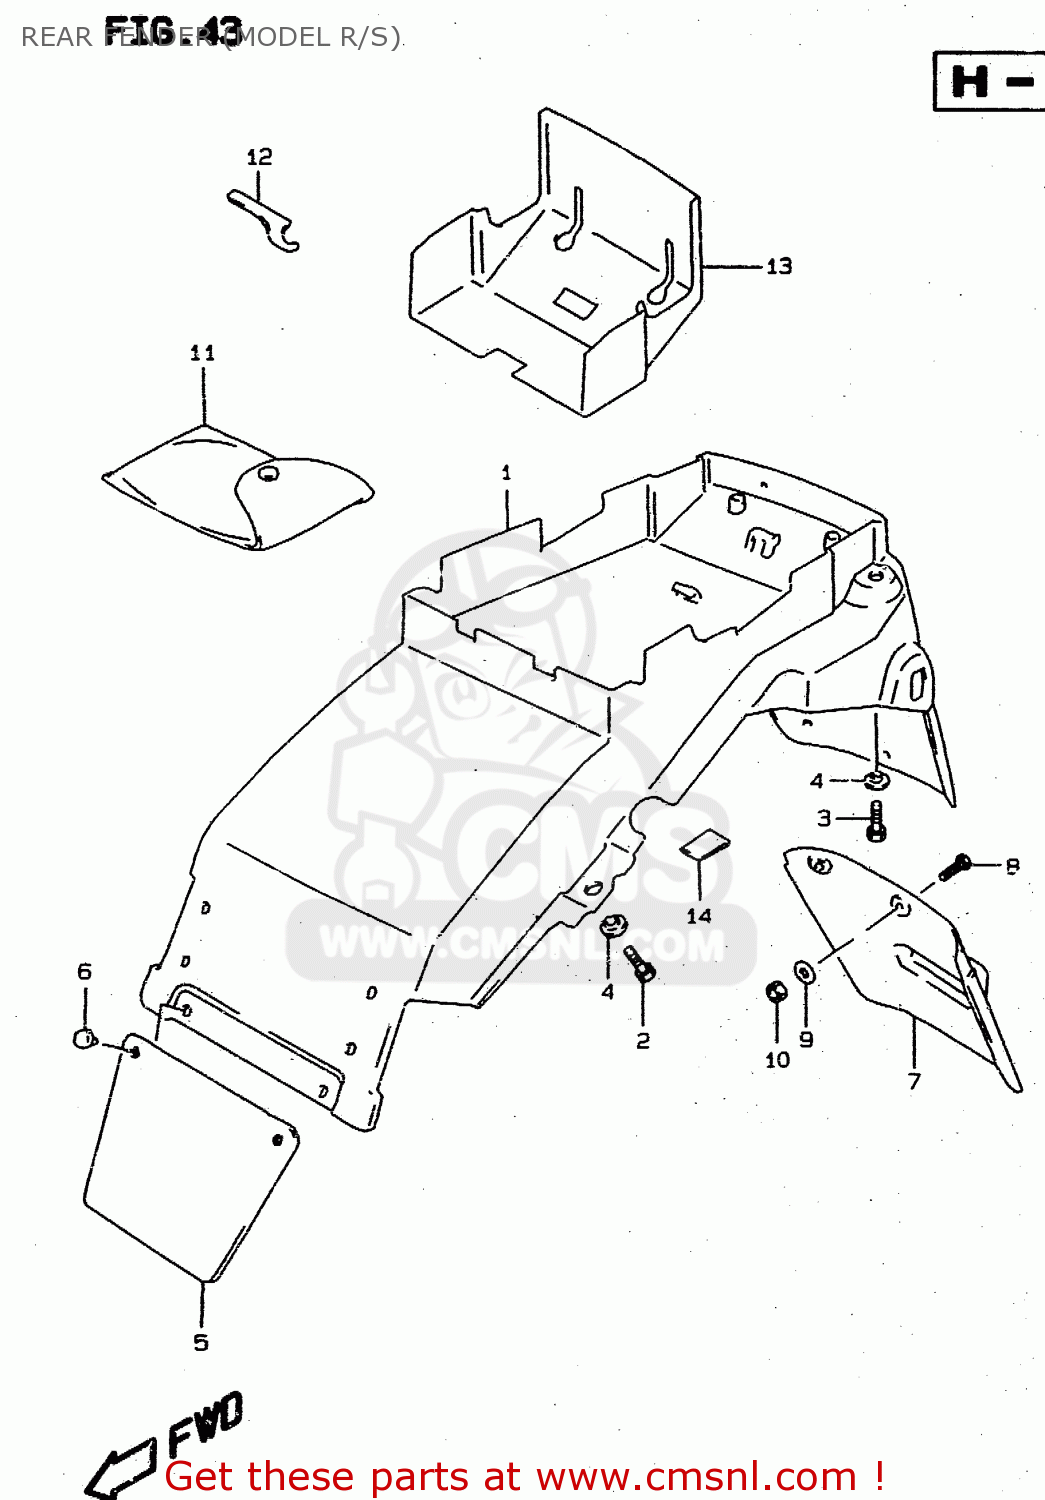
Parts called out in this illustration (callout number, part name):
1	FENDER,RR
2	BOLT
3	BOLT
4	WASHER
5	GUARD,RR FENDER MUD
6	CLIP,MUDGUARD
7	EXTENSION,RR FENDER
8	SCREW
9	WASHER
10	NUT
11	TOOL ASSY
12	CLAMP
13	GUARD,REAR FENDER
14	TAPE,RR FENDER
